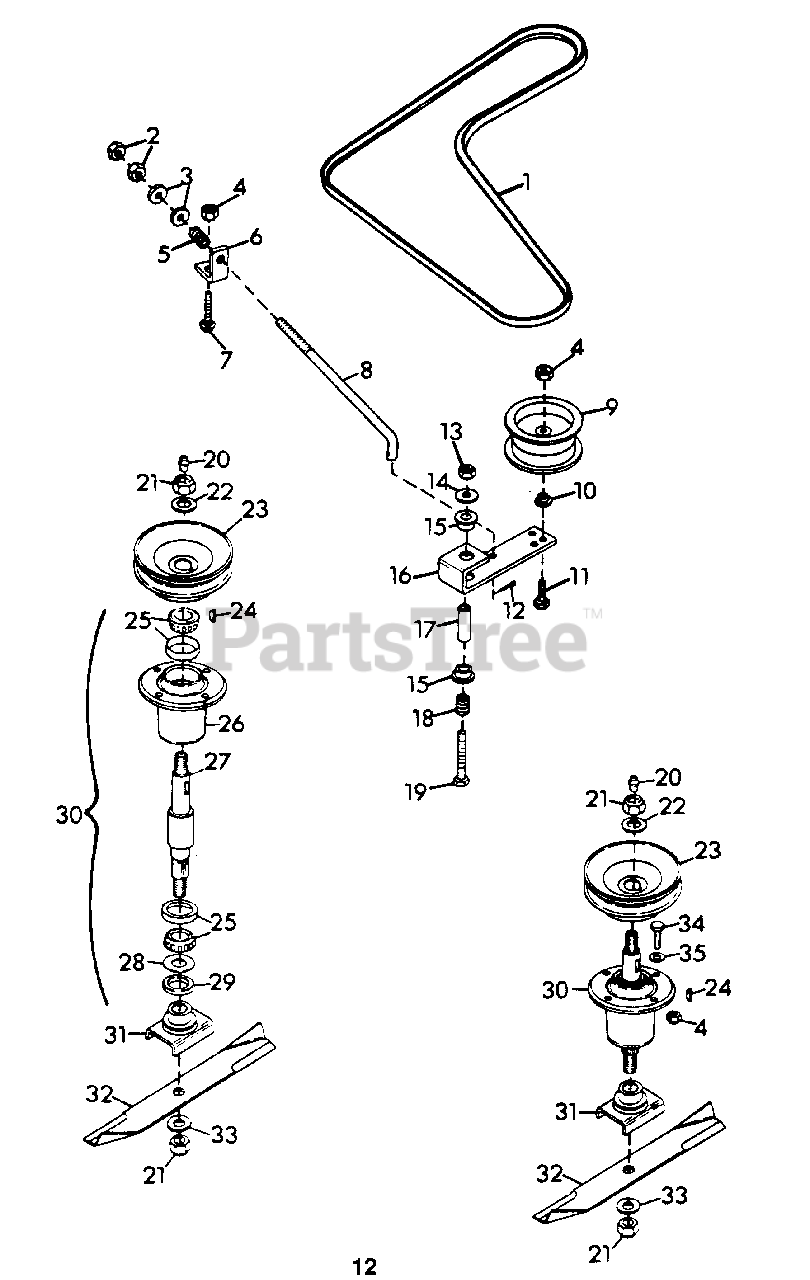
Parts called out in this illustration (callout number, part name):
1	Belt, Pro-40 Mower
2	Nut, Hex 3/8-24
3	Washer, Flat .406x.812x.065
4	Nut, Lock 3/8-16
5	Spring, Comp. 1x.78x338 Lb/N
6	Bracket, Belt Tensioner
7	Bolt, 3/8-16x1.00 Rd Hd Sq Nk
8	Rod, Idler
9	Pulley, Idler
10	Bushing
11	Bolt, Hex 3/8-16x2.25
12	Pin, Cotter .09x.75
13	Nut, Lock 1/2-13
14	Washer, Flat .531x1.250x.100
15	Bushing, Nylon .76x1.00x.600 Flg.
16	Arm, Idler Pivot
17	Spacer
18	Spring, Comp. 1x.80x36 Lb/N
19	Bolt, Hex 1/2-13x3.25
20	Fitting, Lube 1/8
21	Nut, Lock 5/8-11
22	Washer, Flat .687x1.312x.122
23	Sheave, Spindle
24	Key, Woodruff 1/4x1 Hard
25	Assembly, Bearing
26	Housing, Bearing
27	Shaft, Spindle
28	Washer, Flat .975x1.970x.030
29	Seal, Steel
30	Assembly, Spindle
31	Weldment, Blade Cradle
32	Blade
33	Washer, Flat .656x1.312x.095
34	Bolt, Hex 3/8-16x1.25
35	Washer, Flat .438x1.000x.083
